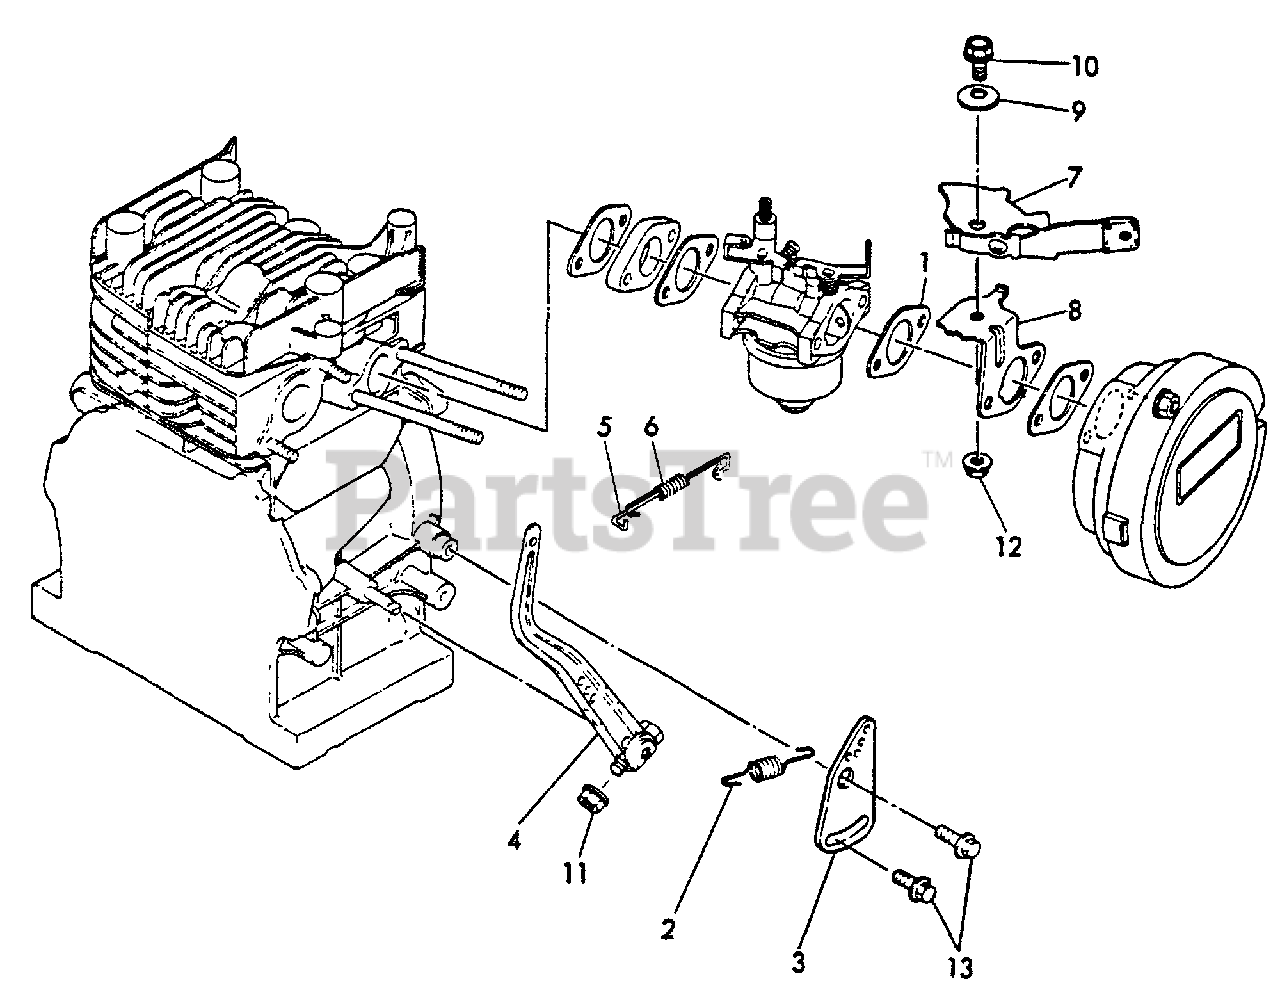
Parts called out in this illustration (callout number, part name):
1	GASKET, INTAKE
2	SPRING, REGULATOR
3	HANDLE, REGULATOR
4	LEVER, GOVERNOR
5	LINK, THROTTLE
6	SPRING
7	LEVEL ASSY
8	BRACKET
9	COLLAR
10	BOLT - 6X12 -- PLATED
11	NUT - 6 -- FLANGE
12	NUT - 6 -- FLANGE
13	BOLT - 6X8 -- PLATED
